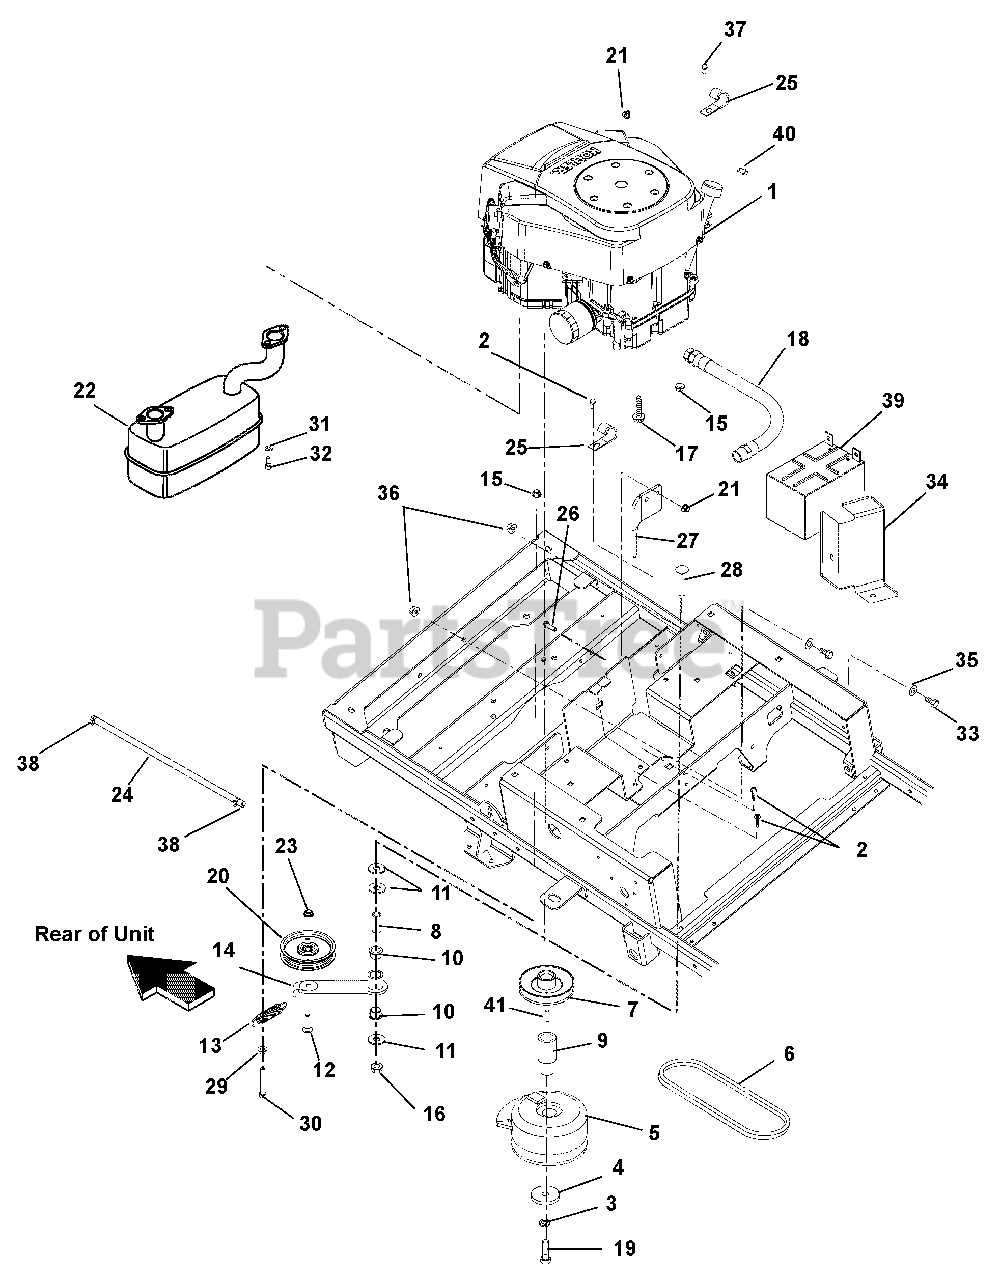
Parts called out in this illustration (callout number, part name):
1	ENGINE, KOHLER TWIN 20 HP
1	TANK, FUEL SCORPION LOGO S/O
1	WLDMT, RESERVOIR GUARD
2	@SCR-TAP .25-20X.37 HWH YWZ TR
3	@WSHR-LK .44X.109 REG YWZC
4	WSHR-FL-STL .469X2.00X.25 YWZC
5	CLUTCH,105FTLB MONOPOLE 6.83"
5	CLUTCH,105FTLB MONOPOLE 6.12"
6	V-BELT, HA-WRAPPED
7	PULLEY, V-1" ID X 4.50" OD
8	BSHG-SLV .500X.750X1.560
9	EXT-CRANKSHAFT LOWER
10	BSHG-FLG 0.75X0.875X.625X1.125
11	@WSHR-FL-STL.563X1.38X.109YWZC
12	@BLT-RDHDSQNK .38-16X1.50 G5YZ
13	SG-TENS .105X.812X3.88 WLD 15
14	WMT, GROUND DRIVE IDLER ARM
15	@NUT-LK-NYL-FLG .38-16 YWZC
16	@NUT-LK-TOP-FLG .50-13 YWZC
17	@SCR-TAP .38-16X1.00 HWH TR YZ
18	OIL DRAIN HOSE
19	BLT-HEX .44-20X4.50 GR8 YWZC
20	ASM, 4" IDLER (.75 WIDE)
21	@NUT-LK-NYL-FLG .31-18 YWZC
22	MUFFLER, KOHLER TWIN COURAGE
23	@NUT-LK-TOP-FLG .38-16 YWZC
24	HOSE, .25 LOW-PERM BULK GAS
25	J-CLAMP
26	@BLT-HEX .31-18X1.00 GR5 YWZC
27	CLUTCH STOP
28	@BLT-RDHDSQNK .50-13X2.50 G5YZ
29	@NUT-SPNLK-FLG .375-16 YWZC
30	@BLT-HEX .38-16X2.50 GR5 YWZC
31	@WSHR-LK .31X.078 REG YWZC
32	SCR-CAP .31-18X.75 S/HD
33	@BLT-HEX .25-20X.75 GR5 YWZC
34	BRKT, BATTERY HOLDER
35	@WSHR-FL-STL.281X.62X.065 YWZC
36	NUT-KEPS .250-20
37	@BLT-HEX .38-16X.75 GR5 YWZC
38	CLAMP, FUEL LINE
39	BATTERY, 12V; 215 CCA GEP
40	BLT-SERHFWH .312-18X.50 YWZC
41	KEY-STR .25X2.0X.25
